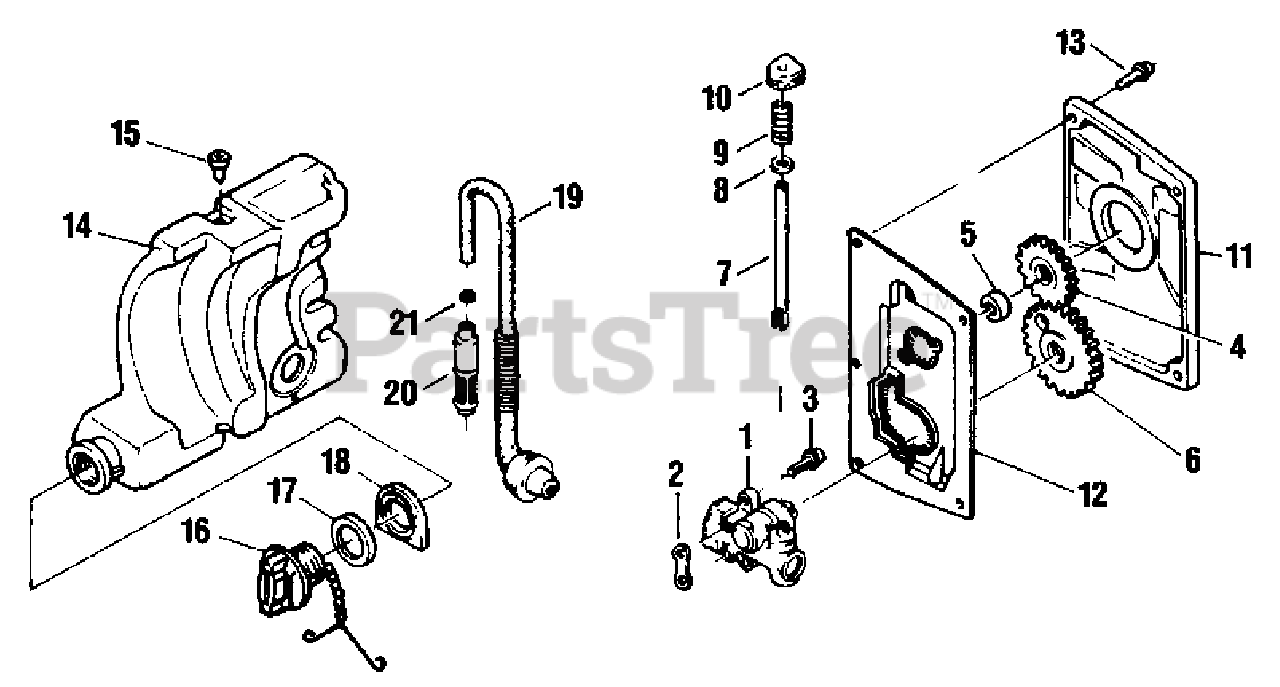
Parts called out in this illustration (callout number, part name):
1	OIL PUMP ASSY
2	GASKET, OIL PUMP
4	PINION
6	GEAR
7	SHAFT, OIL PUMP
8	WASHER 4 MM
11	COVER, PUMP
12	COVER, DUST
14	TANK, OIL
15	VALVE, OIL TANK
16	CAP, OIL
17	GASKET, CAP
18	TANK, OIL
20	CLIP, OIL FILTER
21	CLIP, OIL FILTER
